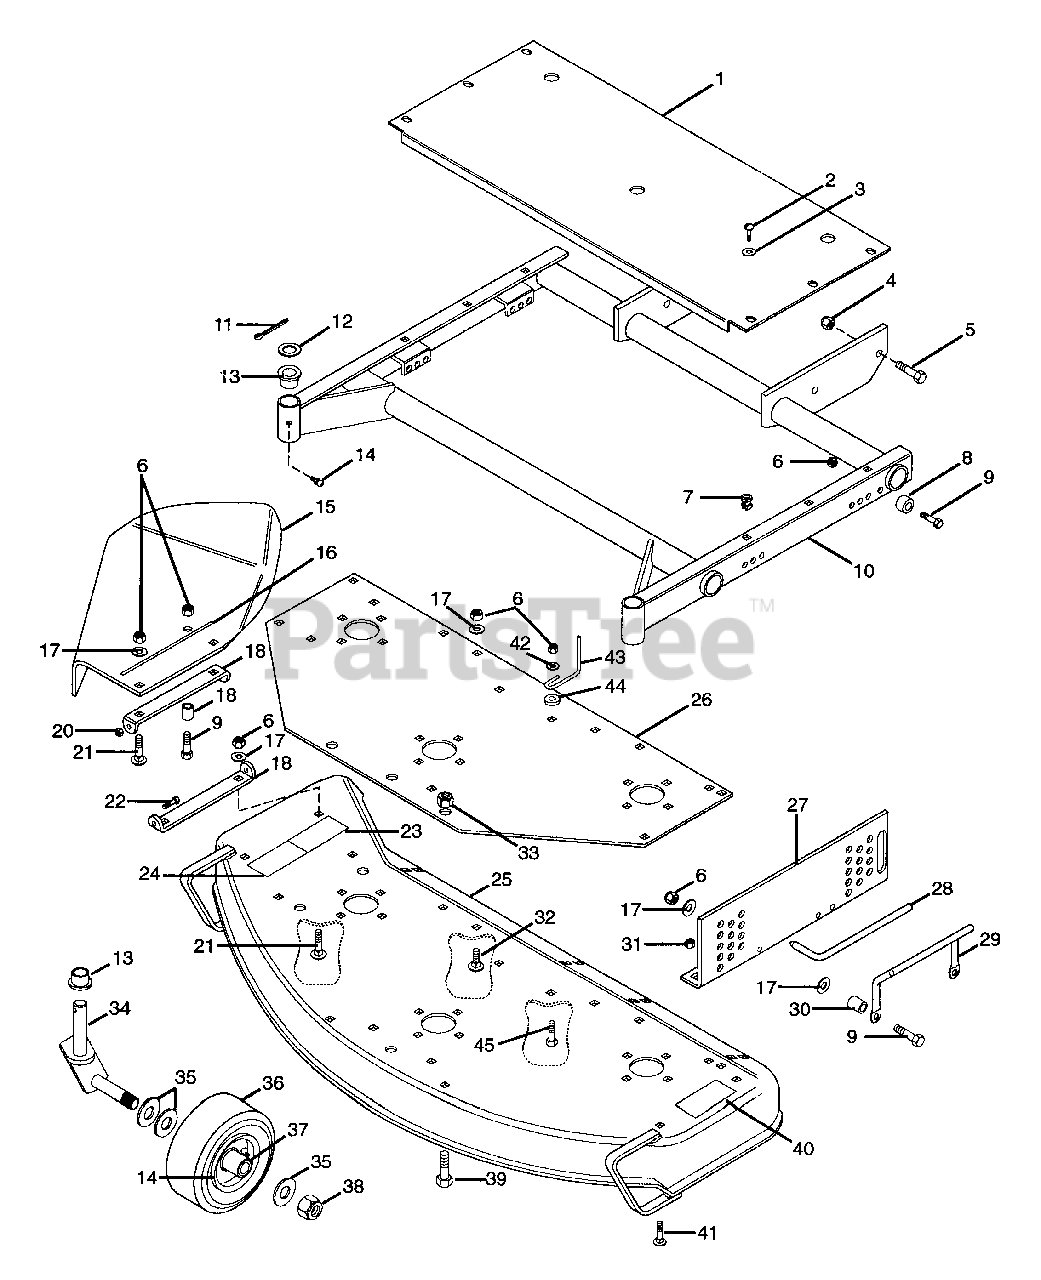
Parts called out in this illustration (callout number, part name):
1	Guard, 50" Mower Belt
2	Screw-Tapping .25-20 x .50
3	Washer-Flat-Steel .281 x .620 x 065
4	Nut-Locking-Nylon .625-11 Grade 2
5	Bolt-Hex .625-11 x 1.50
6	Nut-Locking-Nylon .375-16 Grade 2
7	Grommet, Plastic
8	Bushing .391 x .626 x .670
9	Bolt-Hex .38-16 x 1.50 Grade 5
10	Mower Frame, 50", Pro 150
11	Pin-Cotter .188 x 1.50
12	Washer-Hardened Trust 1.002 x 1.552 x .030
13	Bushing-Flange 1.020 x 1.385 x .75 x 1.75
14	Fitting-Lube .25-28 x .256
15	Shield, Safety External 50" Mower
16	Width of Cut Decal
17	Washer-Flat-Steel .406 x .812 x 065
18	Bracket, Chute
19	Bushing-Sleeve .407 x .625 x .750
20	Nut-Locking-Nylon .250-20 Grade 2
21	Bolt-Round Head Square Neck 38-16 x 1.0
22	Bolt-Hex .25-20 x .875
23	Decal, Danger Hand
24	Decal, Warning Eye
25	Weldment, 50" Mower
26	Plate, Support
27	Bracket, Mower Side Support Left Hand
28	Pin, Mower Locking
29	Handle
30	Bushing
31	Nut-Locking-Nylon .312-18 Grade 2
32	Bolt-Round Head Square Neck .375-16 x .75 Grade 1
33	Nut-Locking-Nylon .50-13 Grade 5
34	Weldment, Caster Fork
35	Washer-Flat .812 x 1.469 x .134
36	Wheel 9 x 3.50
37	Bearing, Ball
38	Nut-Locking-Nylon .75-10 Grade 2
39	Bolt-Hex .50-13 x 1.25 Grade 5
40	Decal, Danger Foot
41	Bolt, Round Head Square Neck 31-18 x 1.0
42	Washer-Flat-Steel .406 x 1.000 x .188
43	Belt Brake Finger 2-Deck Clutch
44	Bushing Flange .383 x .50 x .165
45	Bolt-Hex .38-16 x 1.25 Grade 5
